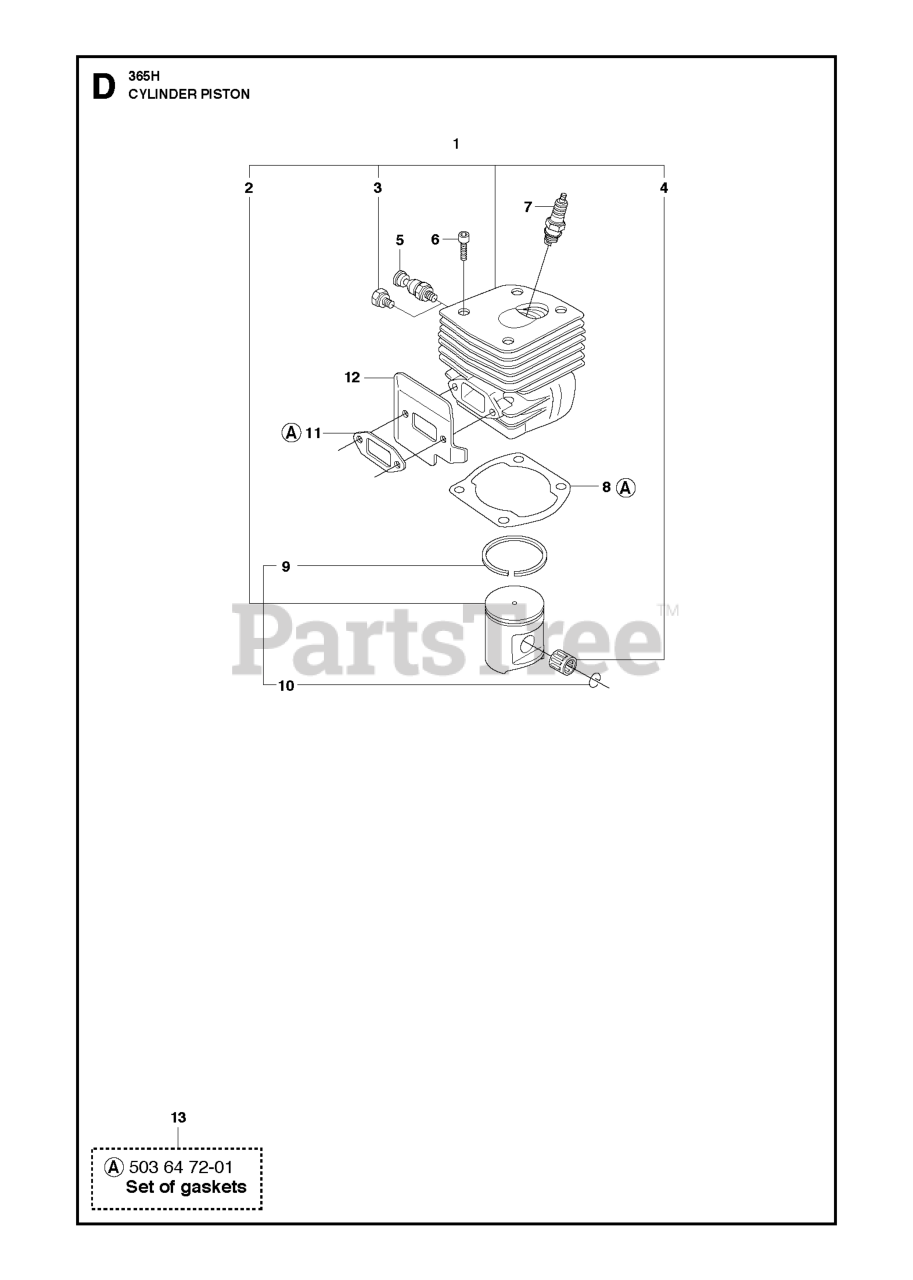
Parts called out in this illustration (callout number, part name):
1	CYLINDER
2	PISTON CPL 48 MM
3	CYLINDER PLUG
4	NEEDLE BEARING PISTON PIN 12X1
5	DECOMPRESSION VALVE
6	SCREW MC6S 5X25
7	SPARK PLUG M14X1.25 NGK BPMR7A
9	PISTON RING
10	WRIST PIN CLIP
13	GASKET SET
